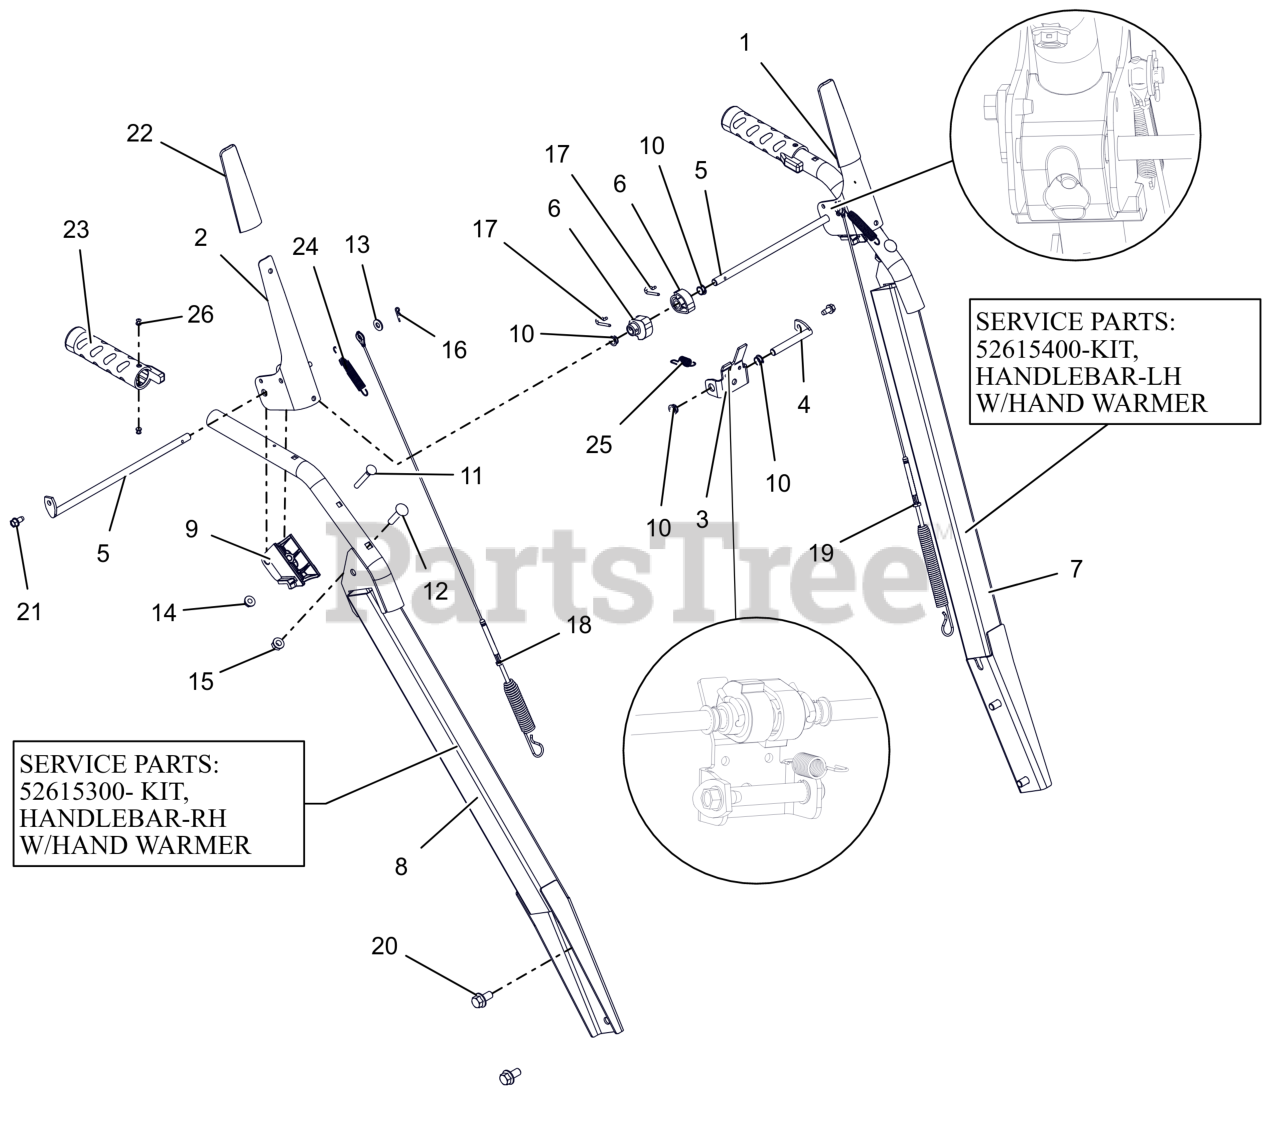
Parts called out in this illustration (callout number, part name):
1	LEVER, CLUTCH-LH
2	LEVER, CLUTCH-RH
3	BRACKET, INTERLOCK ARM
4	ROD, PIVOT - INTERLOCK
5	ROD, PADDLE MOUNT - PRO
6	CAM, INTERLOCK
7	HANDLEBAR, HEAVYDUTY-PRO LH
7	KIT, HANDLEBAR-LH W/WARM GRIP
8	HANDLEBAR, HEAVYDUTY-PRO-RH
8	KIT, HANDLEBAR-RH W/WARM GRIP
9	BLOCK, CLUTCH PADDLE
10	BUSHING, POLYLINER-.38 SNAPIN
11	BLT-RDHDXLSQNK .25-20X2.0 G5YZ
12	BLT,RHSN .31-18X1.50 G5 ZCC
13	WSHR,FLT .281X.625X.065 ZCC
14	NUT-LK-CTR-FLG .25-20 ZC120
15	NUT-LK-TOP-FLG .312-18 GF ZCC
16	PIN, HAIR #178 .06X.77 ZCC
17	PIN, SPRING CLIP
18	CABLE, AUGER (DELUXE & PRO)
19	CABLE, UPPER TRACTION
21	SCR-TAP .25-20X.50 HWH ZCC
22	SLEEVE, CLUTCH PADDLE-GRAY
23	GRIP,HEATED HANDLE-GRAY
24	SPRING, EXTENSION
25	SPRING-EXT .047X.438X1.45
26	RVT-POP #43 .125X.313 STL ZINC
